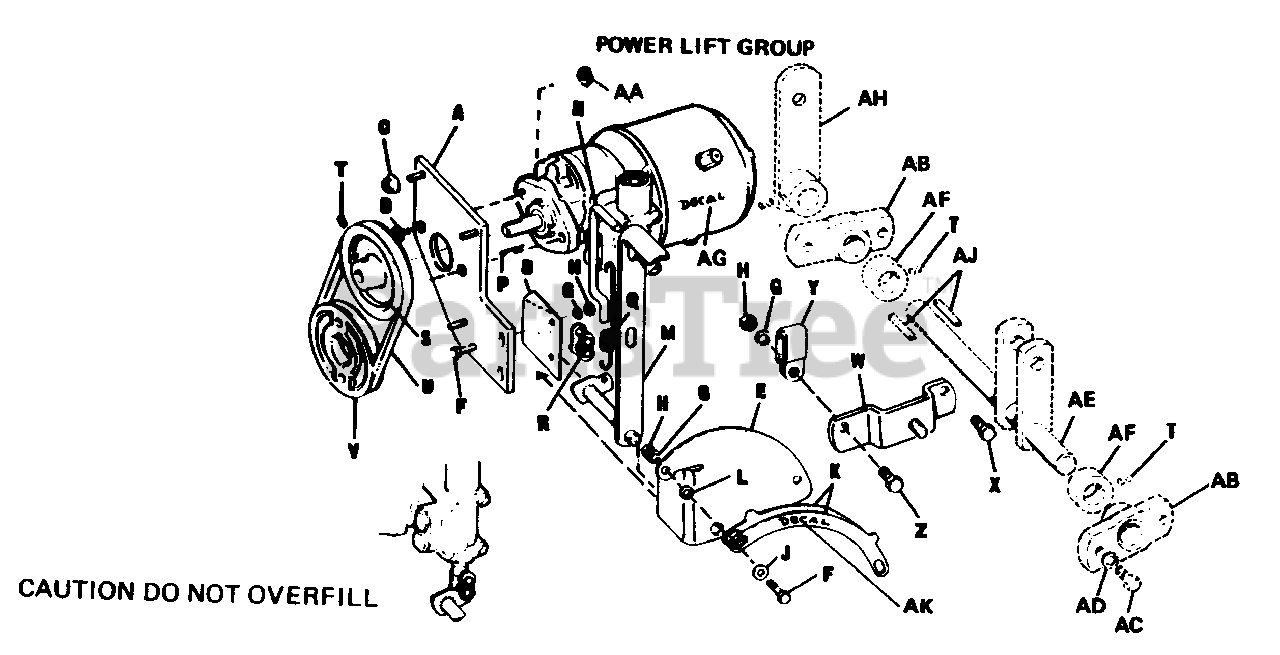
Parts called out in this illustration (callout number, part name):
A	Pump Support Assembly
B	Angle Bracket
C	Hex. Nut, Whiz Lock, 5/16"-18
D	Machine Screw, Flat Hd., 3/8"-16 x 1 1/4"
F	Hex. Cap Screw, 1 /4"-20 x 3/4"
G	Lock Washer, 1/4"
H	Full Hex. Nut, 1/4"-20
J	Plain Washer, 1 /4"
K	Stop Plate
M	Lever Assembly
N	Latch Rod
P	Cotter Pin, 3/32" x 5/8"
R	Connecting Link
S	Pumn Pulley
T	Set Screw, 5/16"-18 x 5/16"
V	Drive Pulley
W	Pivot Bar Assembly
X	Hex. Cap Screw, 5/16"-18 x 1 "
Y	Hose Clamp
Z	Hex. Cap Screw, 1/4"-20 x 1"
AA	Nut, Whiz-Lock Flange, 3/8"-16
AB	Lift Lever Bearing
AC	Hex. Cap Screw, 3/8"-16 x 7/8"
AD	Lock Washer, 3/8"
AE	Lift Shaft Assembly
AF	Set Collar
AH	Front Lift Lever Assembly
